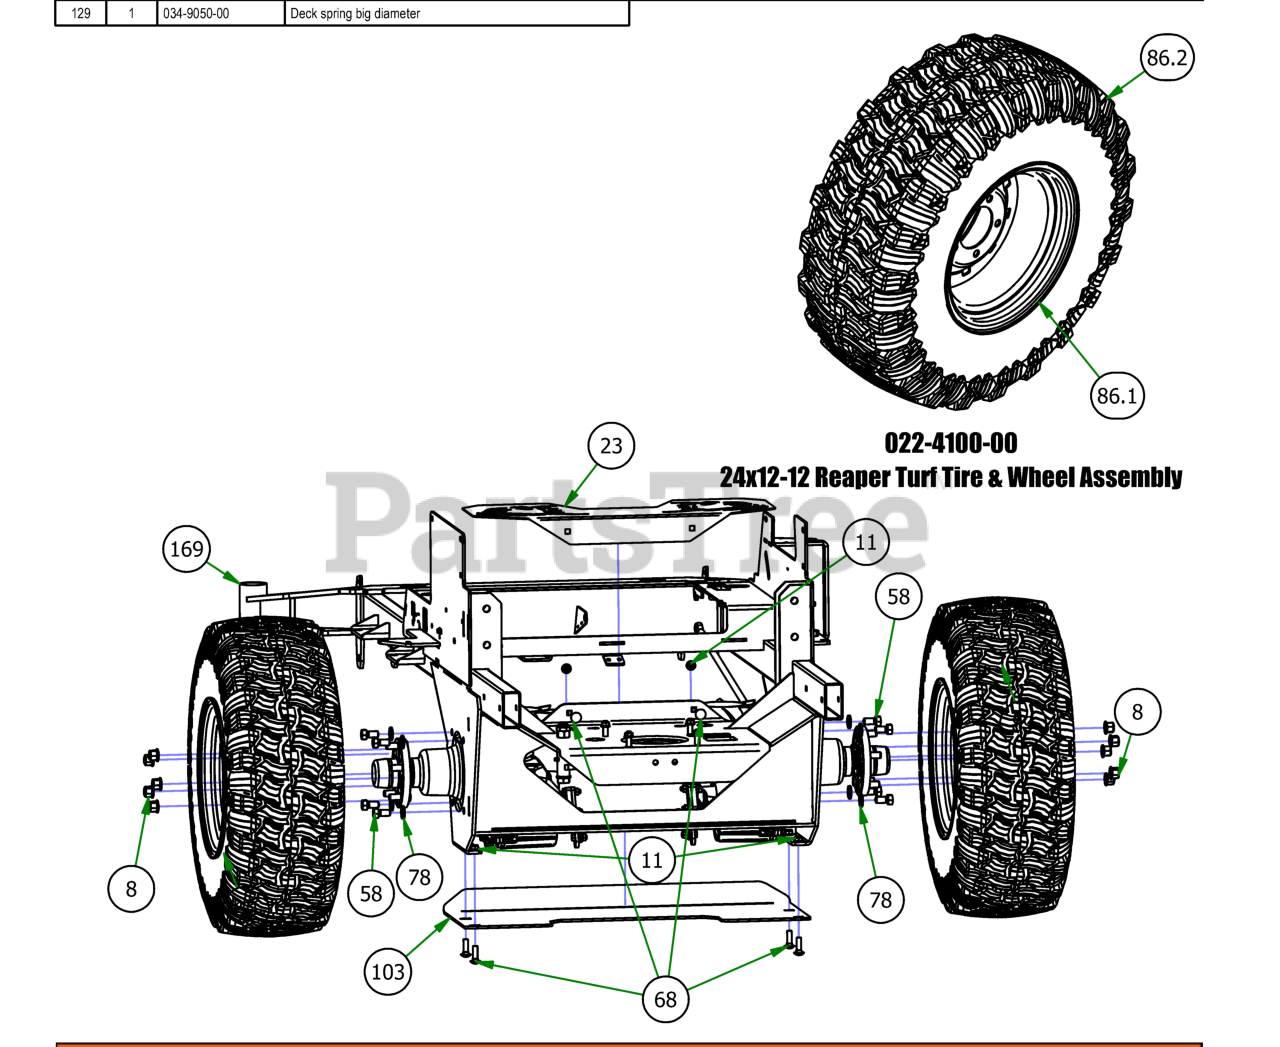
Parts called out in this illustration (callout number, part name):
8	Acorn Lug Nut
11	3/8" Nylock Flange Nut
23	2019 Rigid Fan Guard
58	1/2" x 1" Hex Bolt
68	3/8" x 1 1/4" Carriage Bolt
78	1/2" Lock Washer Zinc
89	24x12-12 Reaper Turf Tire & Wheel Assembly
89.1	12x12" Black Wheel For 2015 Outlaw
89.2	24x12-12 Reaper Turf Tire
103	2019 Outlaw Rigid Skid Plate
142.4	Seal Kit for 4400 Series Outlaw Transaxle
143.5	Hydro Filter for 4400 Transaxle
169	2019 Rebel Frame - Powdercoated
